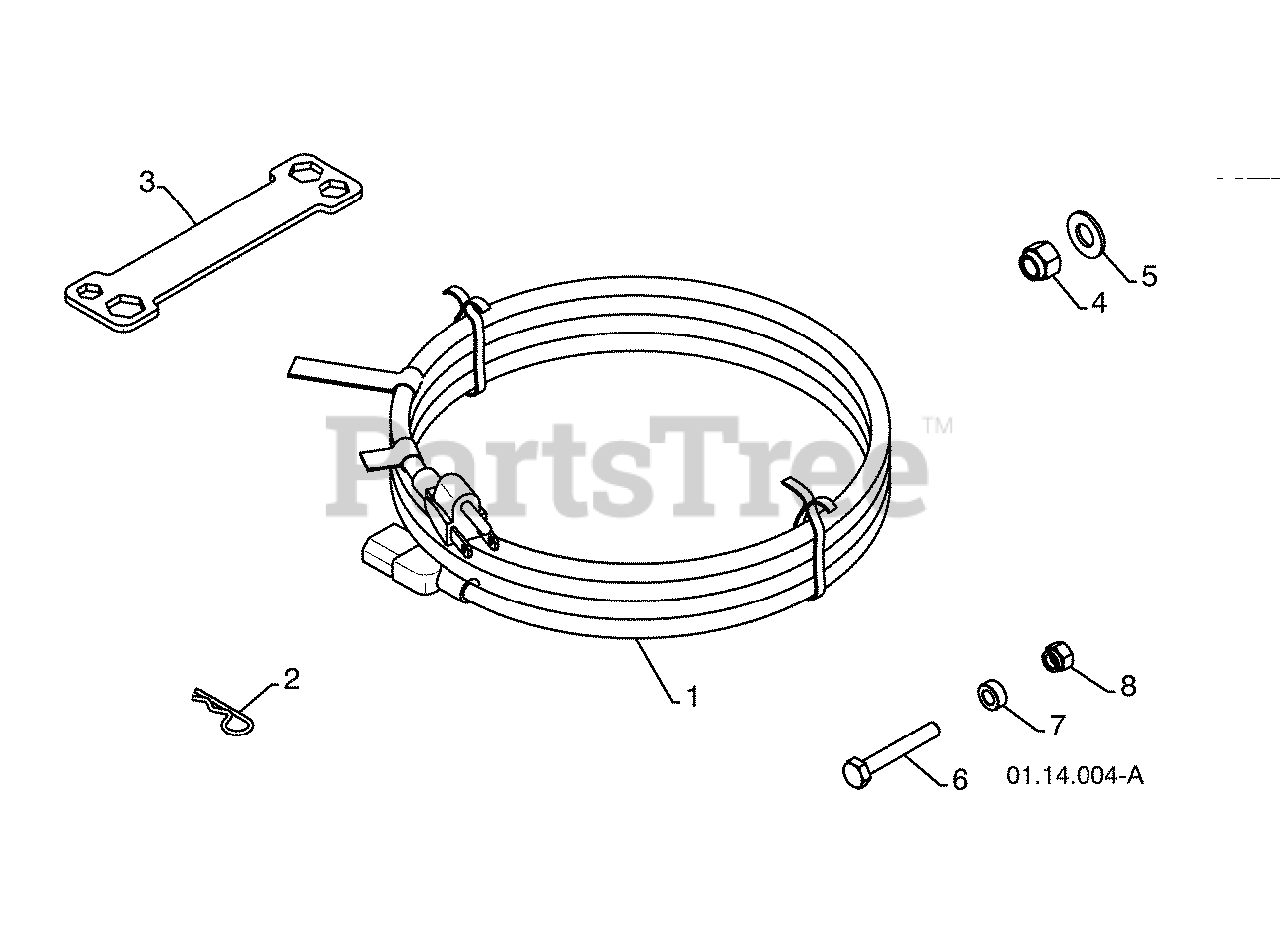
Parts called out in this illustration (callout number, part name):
1	POWER CORD
2	RETAINER PIN
3	WRENCH
4	LOCKNUT 3/8--16
5	WASHER 3/8
6	SHEAR BOLT 1/4--20 X 1--3/4
8	LOCKNUT 1/4--20
